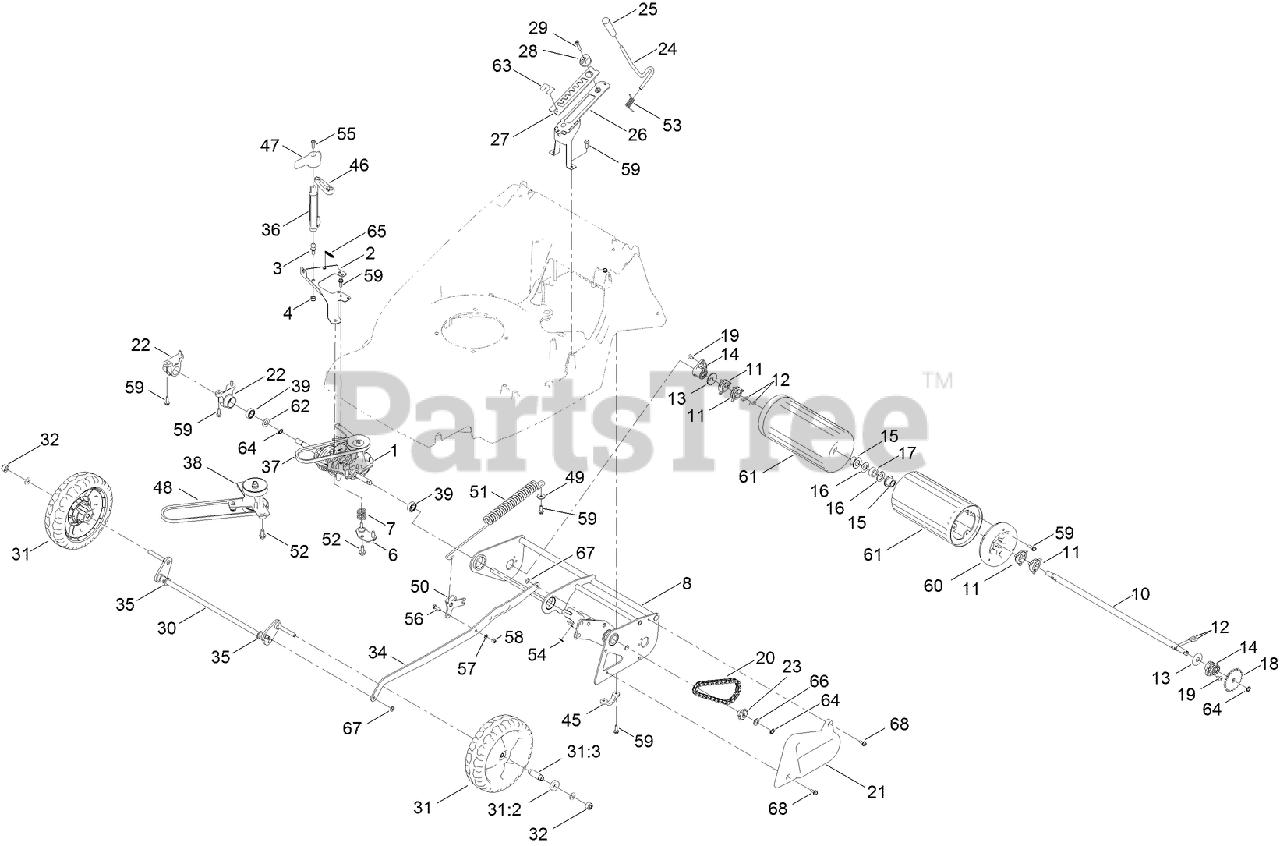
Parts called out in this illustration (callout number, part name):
1	GEARBOX-3 SPEED
2	PLATE-MOUNTING, GEARBOX
3	STUD-BALL
4	NUT-HEX, NI
6	GEARBOX BRACKET ASSEMBLY
7	SPRING-MOUNTING, GEARBOX
8	REAR AXLE FRAME ASSEMBLY
10	SHAFT-ROLLER, PRO
11	CAM-DRIVE
12	KEY-DRIVE
13	WASHER-THRUST
14	BEARING
15	BUSHING-ROLLER, OILITE
16	WASHER
17	SPACER-ROLLER
18	SPROCKET
19	SCREW-TAPTITE
21	COVER-CHAIN
22	MOUNT-BEARING, FRAME (REAR)
23	SPROCKET, 10T
24	LEVER-HOC
25	KNOB-HOC
26	HOC TOWER ASSEMBLY
27	PLATE-HOC
28	ADJUSTER-HOC
29	SCREW-HSH
30	56 FRONT AXLE ASSEMBLY
31:2	BEARING-BALL
31:3	SPACER
32	NUT-HF, NI
34	CONNECTING ROD ASSEMBLY
35	BEARING-AXLE, FRONT
36	ROD-SELECTOR, 3 SPEED
37	V-BELT
38	JACK SHAFT ASSEMBLY
39	BEARING, BALL 12MM
45	AXLE- SUPPORT, REAR
46	ARM-SELECTOR, 3 SPEED
47	KNOB- SELECTOR, 3 SPEED
48	V-BELT
49	WASHER
50	SPRING LOAD LEVER
51	SPRING COUNTER BALANCE
52	SCREW-HWH
53	SPRING-TORSION, HOC
54	GRIP-FIX
55	SCREW
56	SCREW-HH
57	WASHER-PLAIN
58	NUT-NYLOC
59	SCREW-TAPTITE
60	CAP-ROLLER, END
61	ROLLER SHELL ASSEMBLY
62	WASHER-THRUST
63	DECAL-HOC
64	CIRCLIP-EXTERNAL, HD
65	LEVER-SPRING, CLUTCH (RETURN)
66	WASHER-THRUST
67	WASHER-STARLOCK
68	SCREW-TAPTITE
